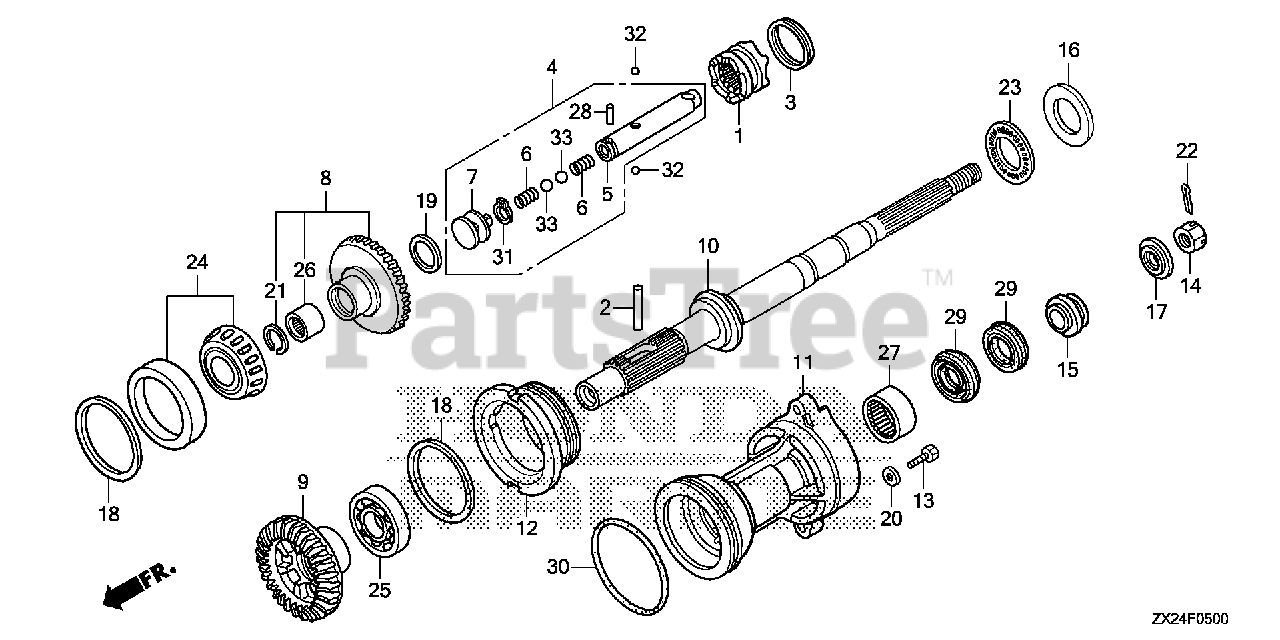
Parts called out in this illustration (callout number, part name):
1	SHIFTER, CLUTCH
2	PIN, SHIFTER (8X50)
3	RING, CROSS PIN
4	SLIDER, SHIFT
5	SLIDER, SHIFT
6	SPRING, SHIFT
7	PLATE, SHIFT
8	GEAR, BEVEL (24T) (FORWARD)
9	GEAR, BEVEL (24T) (REVERSE)
10	SHAFT, PROPELLER
11	HOLDER, PROPELLER SHAFT *NHB14M* (AQUA MARINE SILVER METALLIC)
11	HOLDER, PROPELLER SHAFT *NH565* (GRAND PRIX WHITE)
12	HOLDER, BEARING
13	BOLT, HEX. (12X45)
14	NUT, CASTLE (18MM)
15	WASHER, PROPELLER THRUST
16	WASHER, THRUST BEARING
17	WASHER, PROPELLER
18	SHIM A, BEVEL (0.10)
18	SHIM B, BEVEL (0.15)
18	SHIM C, BEVEL (0.30)
18	SHIM D, BEVEL (0.50)
19	SHIM A, THRUST (2.75)
19	SHIM B, THRUST (2.80)
19	SHIM C, THRUST (2.85)
19	SHIM D, THRUST (2.90)
19	SHIM E, THRUST (2.95)
19	SHIM F, THRUST (3.00)
19	SHIM G, THRUST (3.05)
19	SHIM H, THRUST (3.10)
19	SHIM I, THRUST (2.70)
19	SHIM J, THRUST (2.65)
19	SHIM K, THRUST (2.60)
19	SHIM L, THRUST (2.55)
19	SHIM M, THRUST (2.50)
20	WASHER, PLAIN (12MM)
21	RING, SETTING (39)
22	PIN, SPLIT (4.0)
23	BEARING, THRUST (F)
24	BEARING, TAPER ROLLER (60X100X30)
25	BEARING, RADIAL BALL (55X100X21)
26	BEARING, NEEDLE (28X39X30)
27	BEARING, NEEDLE (32X42X30)
28	ROLLER (3X13.8)
29	SEAL, WATER (30X45X7)
30	O-RING (121X3.1)
31	CIRCLIP (OUTER) (15MM)
32	BALL, STEEL (#7) (7/32)
33	BALL, STEEL (#12) (3/8)
